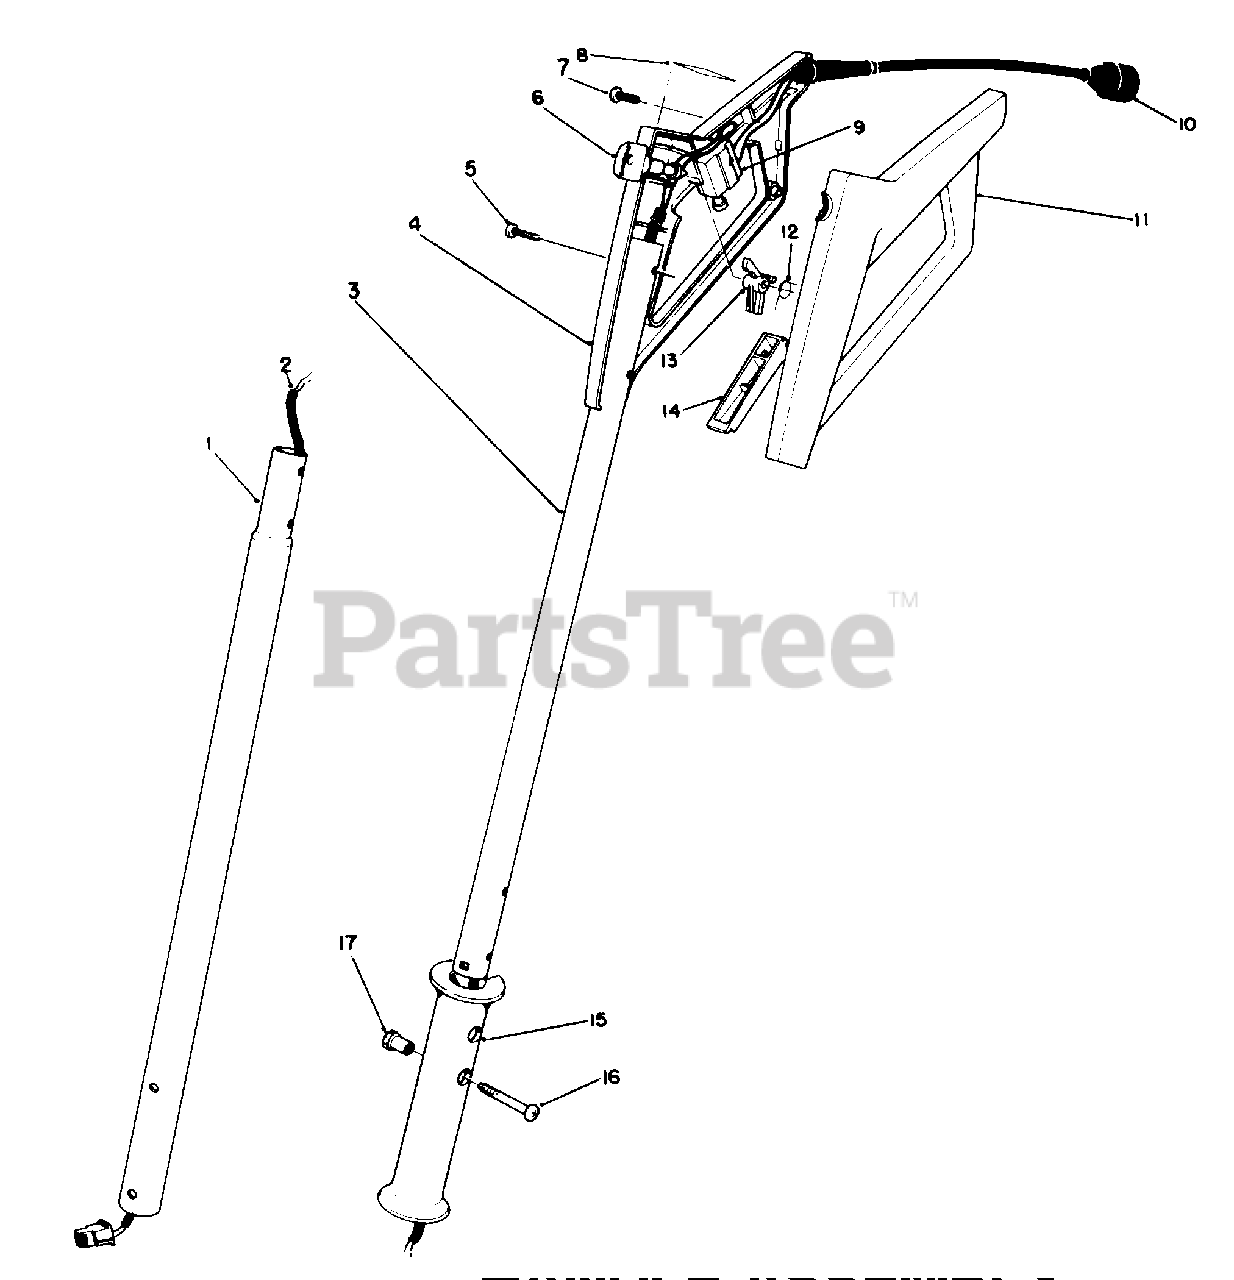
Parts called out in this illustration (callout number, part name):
1	Tube-Lower Handle
2	Wire Harness
3	Tube-Upper Handle
4	Grip-Control R.H.
5	Screw-Pan Head
7	Screw-Pan Head
8	Decal-Control Grip
10	Cord-Supply
11	Grip-Control L.H.
14	Switch Bar
15	Grip-Handle
16	Screw-Pan Head Special
17	Nut-Hex Special
